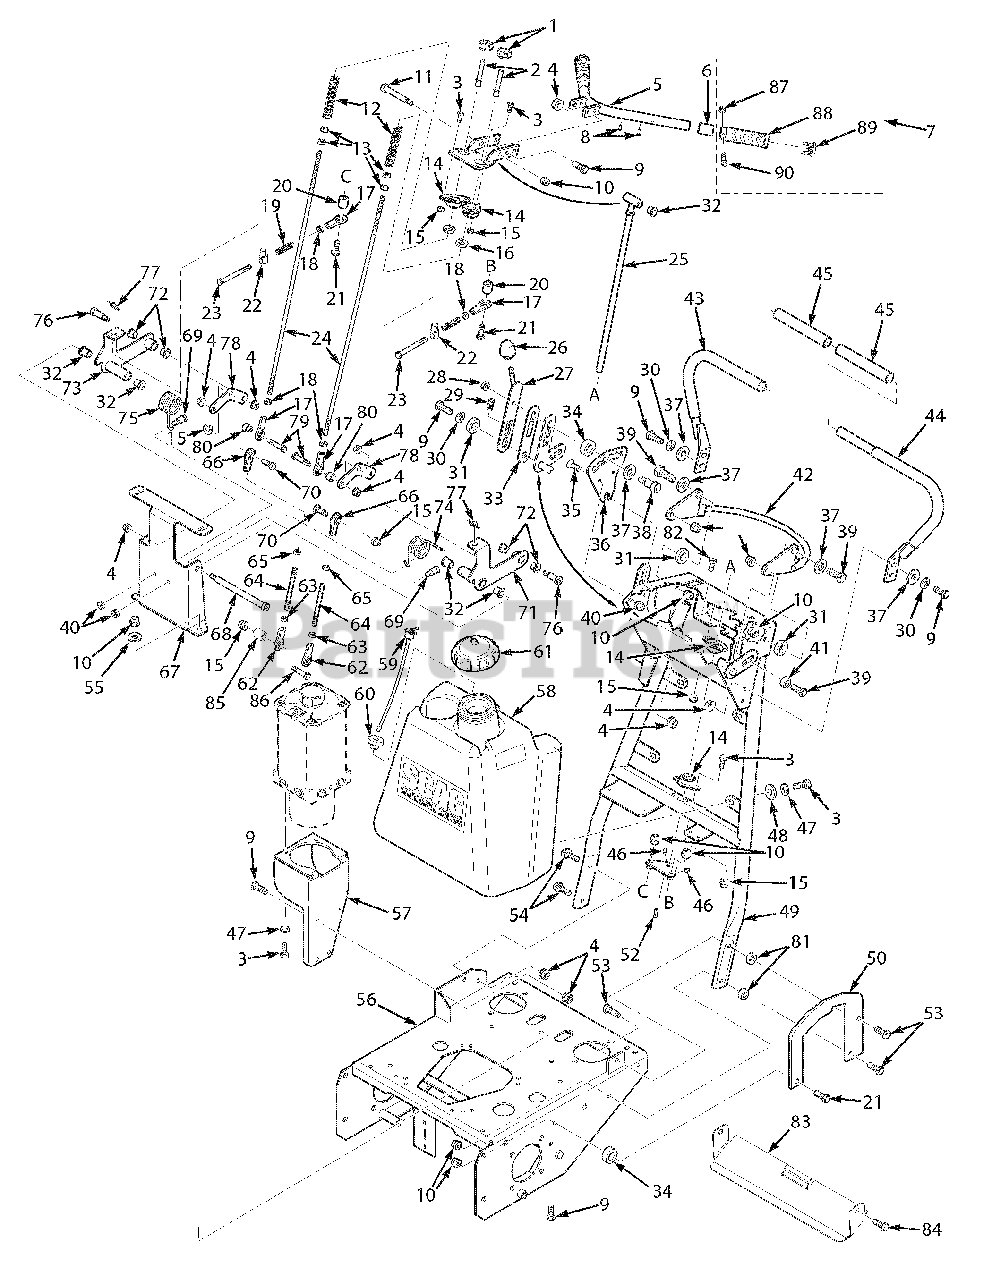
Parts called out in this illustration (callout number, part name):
1	Knob, 3/8-16 Locking
2	Spacer, Tracking
3	Bolt, Hex Head 5/16-18 x 3/4"
4	N ut, Serrated Flange 3/8-16
5	V-Bar Weldment
6	Bearing, Plastic 1" I.D.
7	Sonso Grip
8	Screw, #10-32 x 1/2" Self Tap
9	Bolt, Hex Head 3/8-16 x 1"
10	Nut, Elastic Stop 3/8-16
11	Bolt, Shoulder 1/2 x 2-3/4"
12	Spring, Tracking Adjustment
13	Nut, Jam 3/8-16
14	Bearing, Self Aligning 5/8" I.D.
15	Nut, Elastic Stop 5/16-18
16	Flatwasher
17	Rod End, 3/8-16 Female
18	Nut, Jam 3/8-16 UNC
19	Spring, Tracking Adjustment
20	Spacer
21	Bolt, Hex Head 3/8-16 x 1-1/2"
22	Bushing, Pivot Slide
23	Bolt, Hex Head 3/8-24 x 3-1/2"
24	Rod, Tracking
25	Steering Shaft Weldment
26	Knob, Shifter
27	Handle Weldment, Speed Control
28	Nut, Serrated Flange
29	Spring, Speed Control Slide
30	Lockwasher, 3/8" Spring
31	Bushing, Speed Adjust Lever
32	Bearing, PLastic 1/2" I.D.
33	Slide, Speed Control
34	Spacer
35	Capscrew, 1/4-20 x 3/4"
36	Detent Plate
37	Flatwasher, 3/8-.391 x .938 x .105
38	Bolt, Shoulder
39	Bolt, Hex Head 3/8-16 x 1-1/4"
40	Nut, Elastic Stop 1/4-20
41	Sleeve
42	Reference Bar Weldment
43	Stability Bar Weldment, RH
44	Stability Bar Weldment, LH
45	Grip, Control Lever
46	Set Screw, 1/4-28 x 1/4"
47	Lockwasher, 5/16" Spring
48	Flatwasher, 5/16-.344 x .688 x .065
49	Handle Bar Weldment
50	Deck Latch Arc
51	Steering Plate Weldment
52	Key, 3/16 x 3/16 x 3/4"
53	Bolt, Serrated Flange 3/8-16 x 1-1/2"
54	Bolt, Serrated Flange 3/8-16 x 1-1/4"
55	Flatwasher, 3/8-.391 x .938 x .105 HD
56	Engine Deck Weldment
57	Oil Reservoir Mounting Bracket
58	Fuel Tank Assembly
59	Fuel Pick Up Line
60	Bushing, .56 Dia. Viton
61	Cap, Fuel Tank
62	Rod End, 5/16-24 RH Female
63	Nut, 5/16-24 UNF Jam
64	Link, Pump to V-Bar 5/16-24
65	Nut, 5/16-24 UNF Jam LH
66	Rod End, 5/16-24 LH Female
67	Control Pivot Base
68	Bolt, Shoulder 1/2 x 6"
69	Bolt, Shoulder 5/16 x 3/8"
70	Bolt, Hex Head 5/16-18 x 1-1/4"
71	Steering Arm Assembly, LH
72	Bearing, Plastic
73	Steering Arm Assembl,RH
74	Steering Return Spring, LH
75	Steering Return Spring, RH
76	Bolt, Shoulder 1/2 x 1"
77	Pin, Rue Cotter 1/2" Dia.
78	V-Link
79	Bolt, Hex Head 3/8-16 x 3/4" Grade 8
80	Spacer, V-Link to Tracking Rod
81	Spacer
82	Bolt, Hex Head 5/16-18 x 3/4"
83	Shield, Pump
84	Bolt, Serrated Flange 5/16-18 x 3/4"
85	Spacer, V-Link to Pump
86	Bolt, Hex Head 3/8-16 x 1-3/4"
87	Nut, Metric M5 x 0.8
88	Grip, Magura
89	Cap, Grip End
90	Socket Head Cap Screw, 5mm - 0.8 x 30mm
